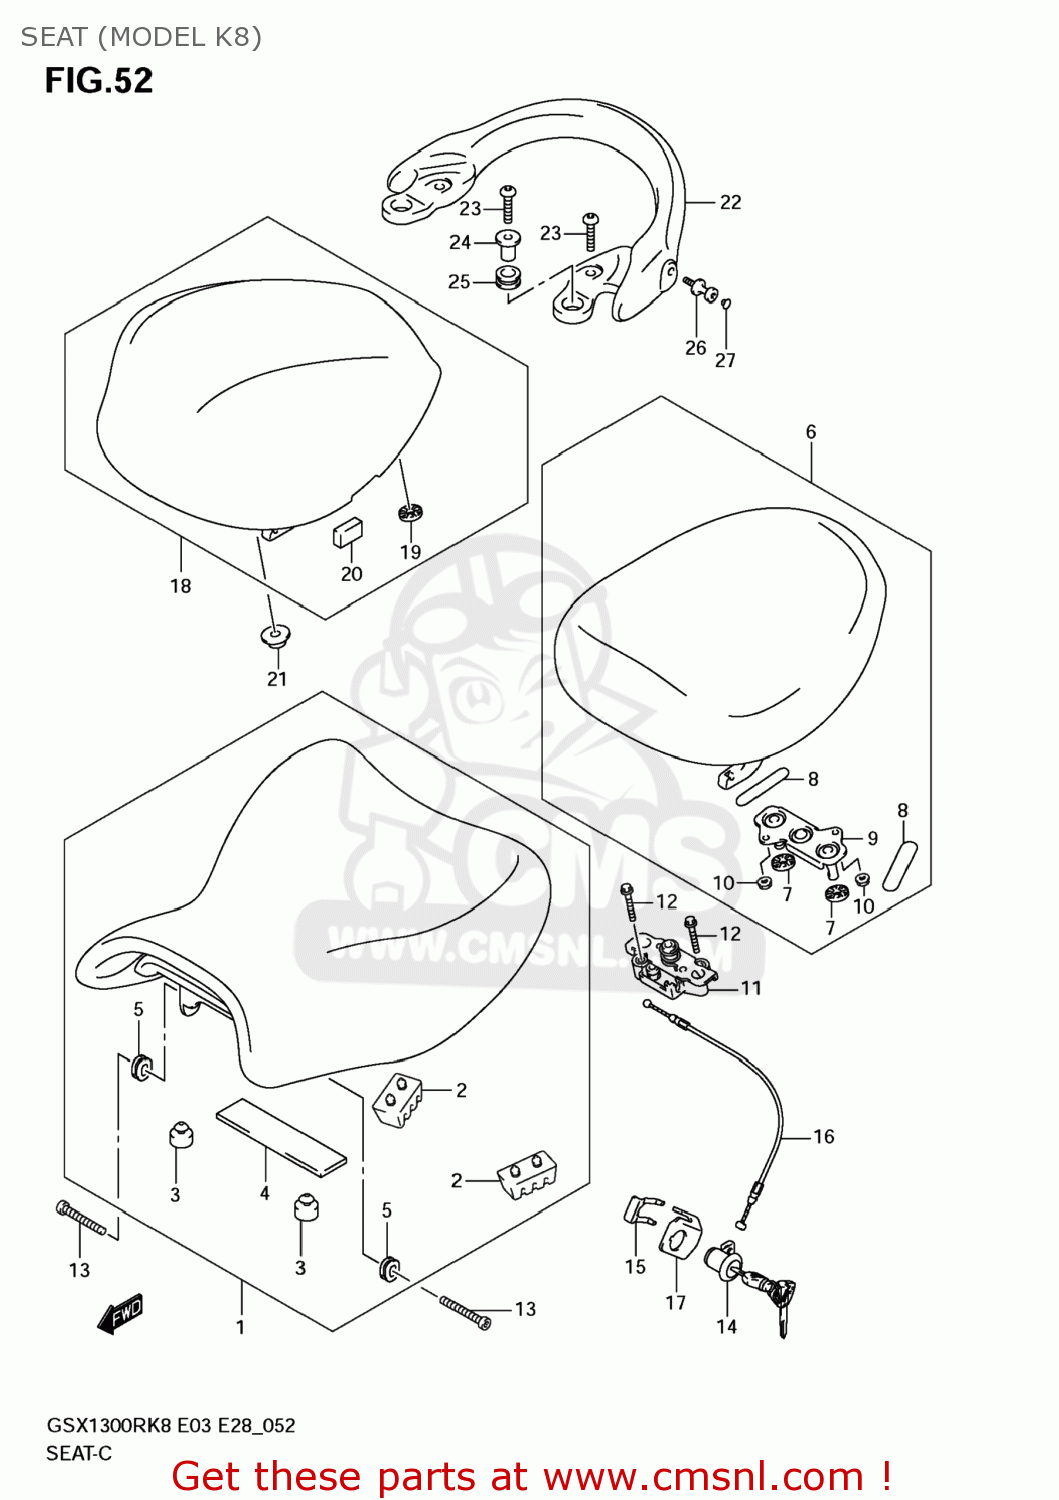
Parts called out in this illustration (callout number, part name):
1	SEAT ASSY
2	CUSHION,SUPPORT(50X25X32)
3	CUSHION
4	CUSHION
5	CUSHION
6	SEAT ASSY,PILL
7	CUSHION
8	CUSHION
9	STRIKER,SEAT LOCK
10	NUT
11	BRACKET,STRIKER SUPPORT
12	BOLT
13	BOLT,SEAT FR
14	LOCK SET,SEAT
15	PLATE,SEAT LOCK ASSY
16	CABLE,SEAT LOC
17	GUIDE,SEAT LOCK CABLE
18	BOX COMP,SEAT
19	CUSHION
20	CUSHION
21	WASHER,FRAME COVER
22	HANDLE,PILLION RIDER
23	BOLT(8X33)
24	WASHER,PILLION
25	CUSHION,PILLION RIDER HANDLE
26	HOOK,PILLION RIDER HANDLE
27	CAP(OD:10)
